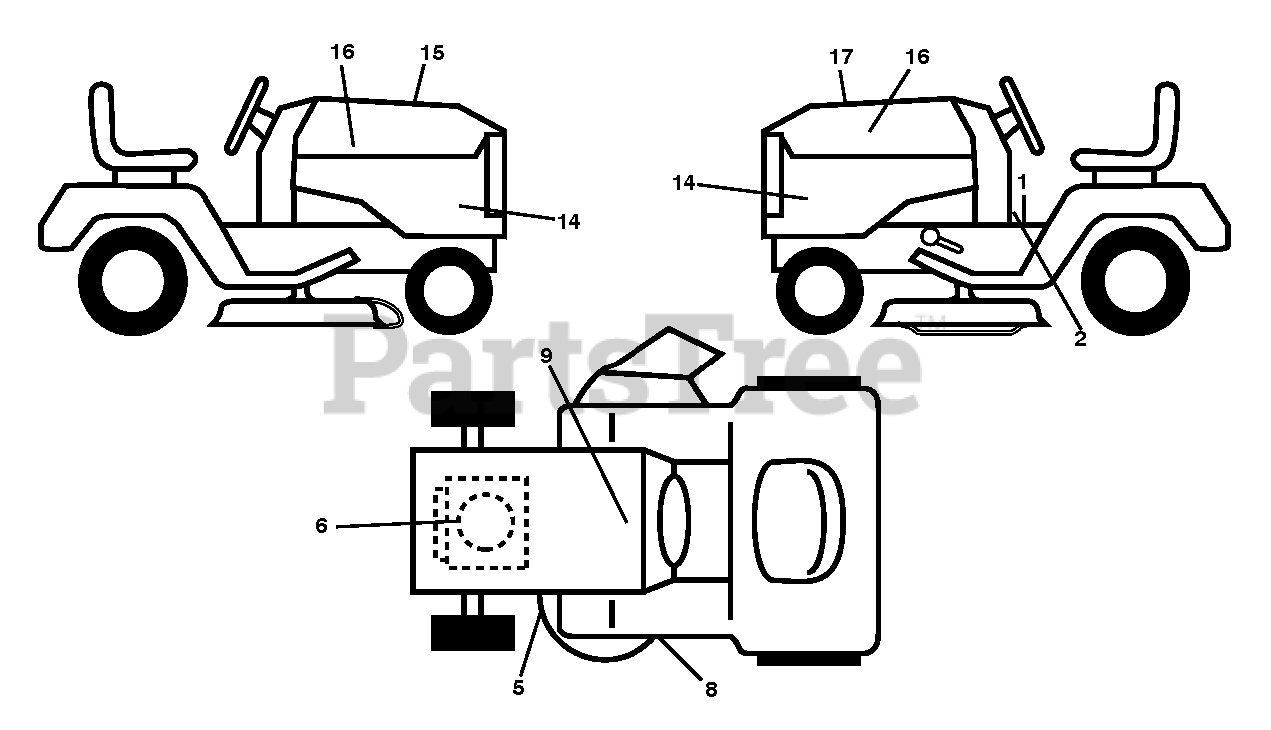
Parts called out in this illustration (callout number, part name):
1	DECAL.FENDER.WARNING
2	DECAL, WARNING SPARK ARRESTOR
5	DECAL.MOWER
6	DECAL.ENG.BS.23HP.XRD.TWIN
8	DECAL.MOWER.SCH.48/54
9	DECAL BTRY SYMBOLS
14	DECAL.SDPNL.HUSQ.GT2.YTH23V48
15	DECAL.WARNING.CUST.RESP.E85.
16	RP.DECAL.BADGE.170MM.TEXTLOGO
17	DECAL.RPL.BSM44.INK.TLW.48.K46
